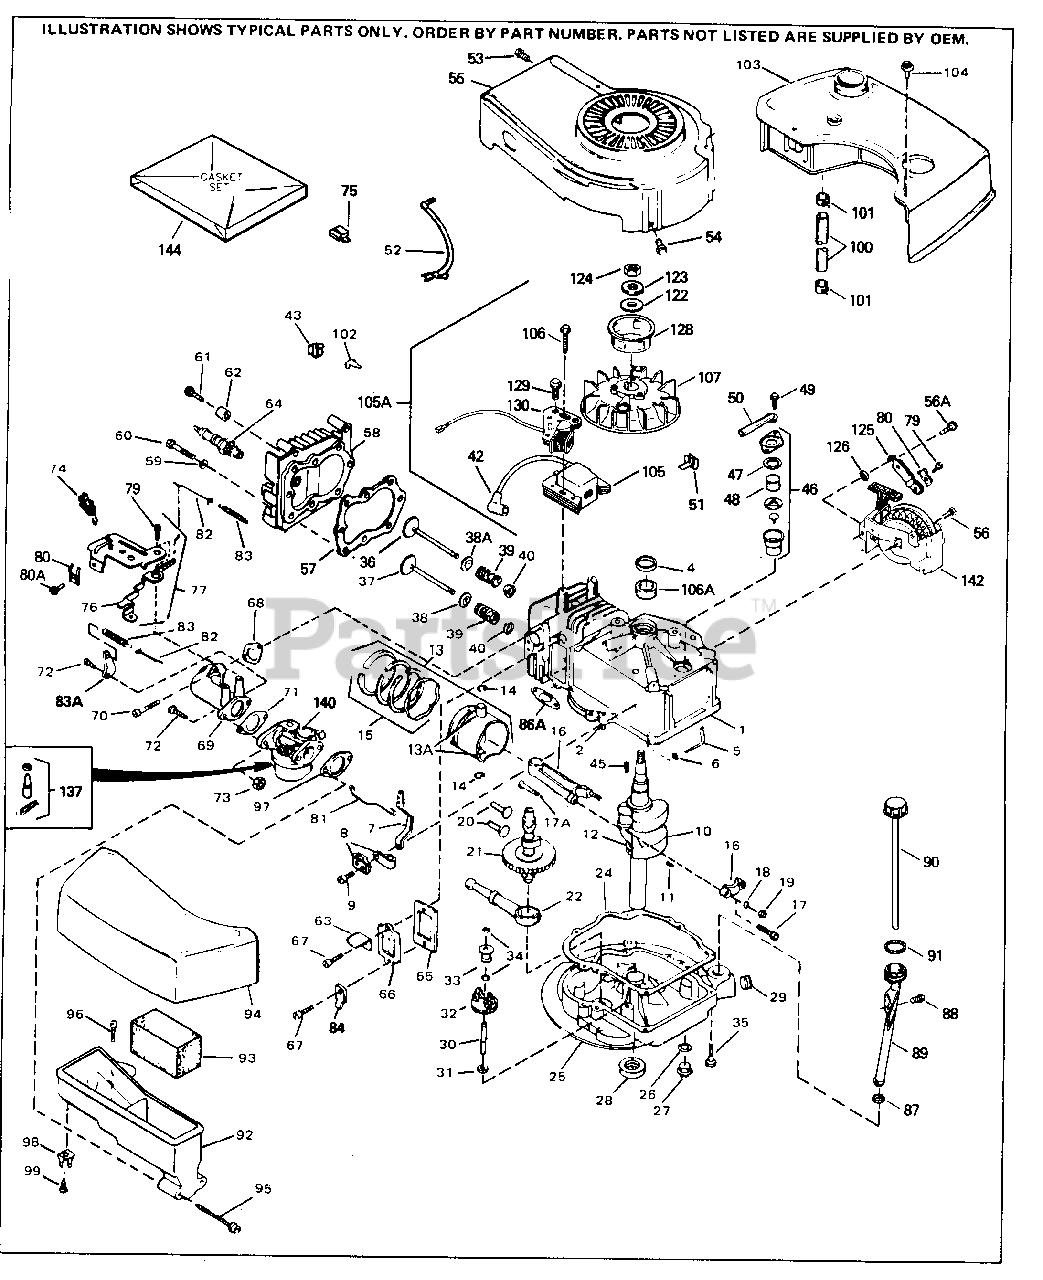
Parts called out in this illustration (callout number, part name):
1	"Cylinder (Incl. 2 & 4) (2-5/8" Bore)
2	Dowel Pin
4	Seal, Oil
5	Rod, Governor (Incl. 6)
6	Flat Washer
7	Lever, Governor
8	Clamp, Governor lever Clamp is positi oned towardsspark plug end on 1977-78 and latermodels. It is positioned op posite spark plugend on earlier model s.
9	Screw, 8-32 x 5/16"
10	Crankshaft
11	Pin, Crankshaft gear duction)
12	Gear, Crankshaft Not serviceable on l ate production
13	Piston, Pin & Ring Set (Std.) 2-5/8" Bore
13	Piston, Pin & Ring Set (.010" OS)
13	Piston, Pin & Ring Set (.020" OS)
13A	Piston & Pin Ass'y. (Incl. 14)(Std.) 2-5/8"
13A	Piston & Pin Ass'y. (Incl. 14) .010" OS
13A	Piston & Pin Ass'y. (Incl. 14) .020" OS
14	Piston Pin Retaining Ring
15	Ring Set (Std.) (2-5/8" Bore)
15	Ring Set (.010" OS)
15	Ring Set (.020" OS)
16	Rod Assy., Connecting (Incl. 17)
17	Bolt, Connecting rod
20	Valve Lifter
21	Camshaft (MCR)
22	Oil Pump Ass'y.
24	* Gasket, Mounting flange
25	Flange Ass'y. (Incl. 26, 27, 28 & 30)
26	* Drain Plug Gasket Not req. w/plastic plug
27	Plug, Oil drain
28	Oil Seal
30	Shaft, Mechanical governor
31	Washer, Flat
32	Gear Assy., Governor (Incl. 31)
33	Spool, Governor
34	Retaining Ring
35	Screw, 1/4-20 x 1-1/4"
36	Intake Valve (Std.) (Incl. 151)
36	Exhaust Valve (1/32" OS) (Incl. 151)
37	Exhaust Valve (Std.) (Incl. 151)
37	Exhaust Valve (1/32" OS) (Incl. 151)
38	Cap, Upper valve spring
38A	Cap, Upper valve spring (Intake)
39	Spring, Valve (Exhaust)
40	Cap, Lower valve spring
42	Cover, Spark plug (Use as required)
45	Key, Flywheel
46	Breather Ass'y. (Incl. 47 thru 51)
47	* Gasket, Breather
48	Element, Breather
49	Screw, 10-24 x 9/16"
50	Tube, Breather
51	Clip, Breather tube
52	Ground Wire
53	Screw, 10-24 x 9/16"
54	Screw, 1/4-20 x 5/8"
55	Housing, Blower
57	* Gasket, Cylinder head
58	Head, Cylinder
59	Washer tion)
60	Screw, 5/16-18 x 1-1/2"
64	Resistor Spark Plug - RJ17LM
64	Resistor Spark Plug (RJ-17LM)
65	* Gasket, Valve spring cover
66	Cover, Valve spring box
67	Screw, 10-24 x 1/2"
68	* Gasket, Intake pipe
69	Pipe, Intake (Incl. 68)
70	Screw, 1/4-20 x 1"
71	* Gasket, Carburetor
72	Screw, 1/4-28 x 7/8"
73	Nut & Lock Washer 1/4-28
74	Terminal Assy. (Use as required)
75	Connector
81	Link, Throttle
82	Link, Governor spring
83	Spring, Governor
83A	Lever, Speed adjusting
86A	* Gasket, Muffler
87	Gasket, Oil fill tube
88	Screw, 10-32 x 1/2"
89	Tube, Oil filler
90	Dipstick, Oil (Incl. 91)
91	"O" Ring
92	Body, Air cleaner
93	Air Filter
94	Cover, Air cleaner
95	Screw, 10-32 x 1-29/32"
96	Screw, 10-24 x 11/16"
97	* Gasket, Air cleaner
100	Fuel Line (Braided 16")
101	Fuel Line Clamp
102	Wire Clip
103	Fuel Tank (Incl. 101)
104	Screw, 10-32 x 35/64"
105	Magneto-to-Solid State Conversion Kit (Includes solid state module, Solid State Flywheel Key, and instructions) (Use as required on external ignitio n engines only)
105A	Milliamp Alternator Conversion Kit Ki t Includes 75, 129, 130 &610885, 6101 18 & 730207 Conversion Kit
106	Screw, 10-24 x 1"
123	Washer, Belleville
124	Nut, Flywheel
137	Inlet Needle, Seat & Clip Assy.
140	Carburetor (Incl. 71, 72, 95 & 137) ( Refer to Division 5, Section A, page 162 for breakdown)
144	* Gasket Set (Incl. items marked *)
